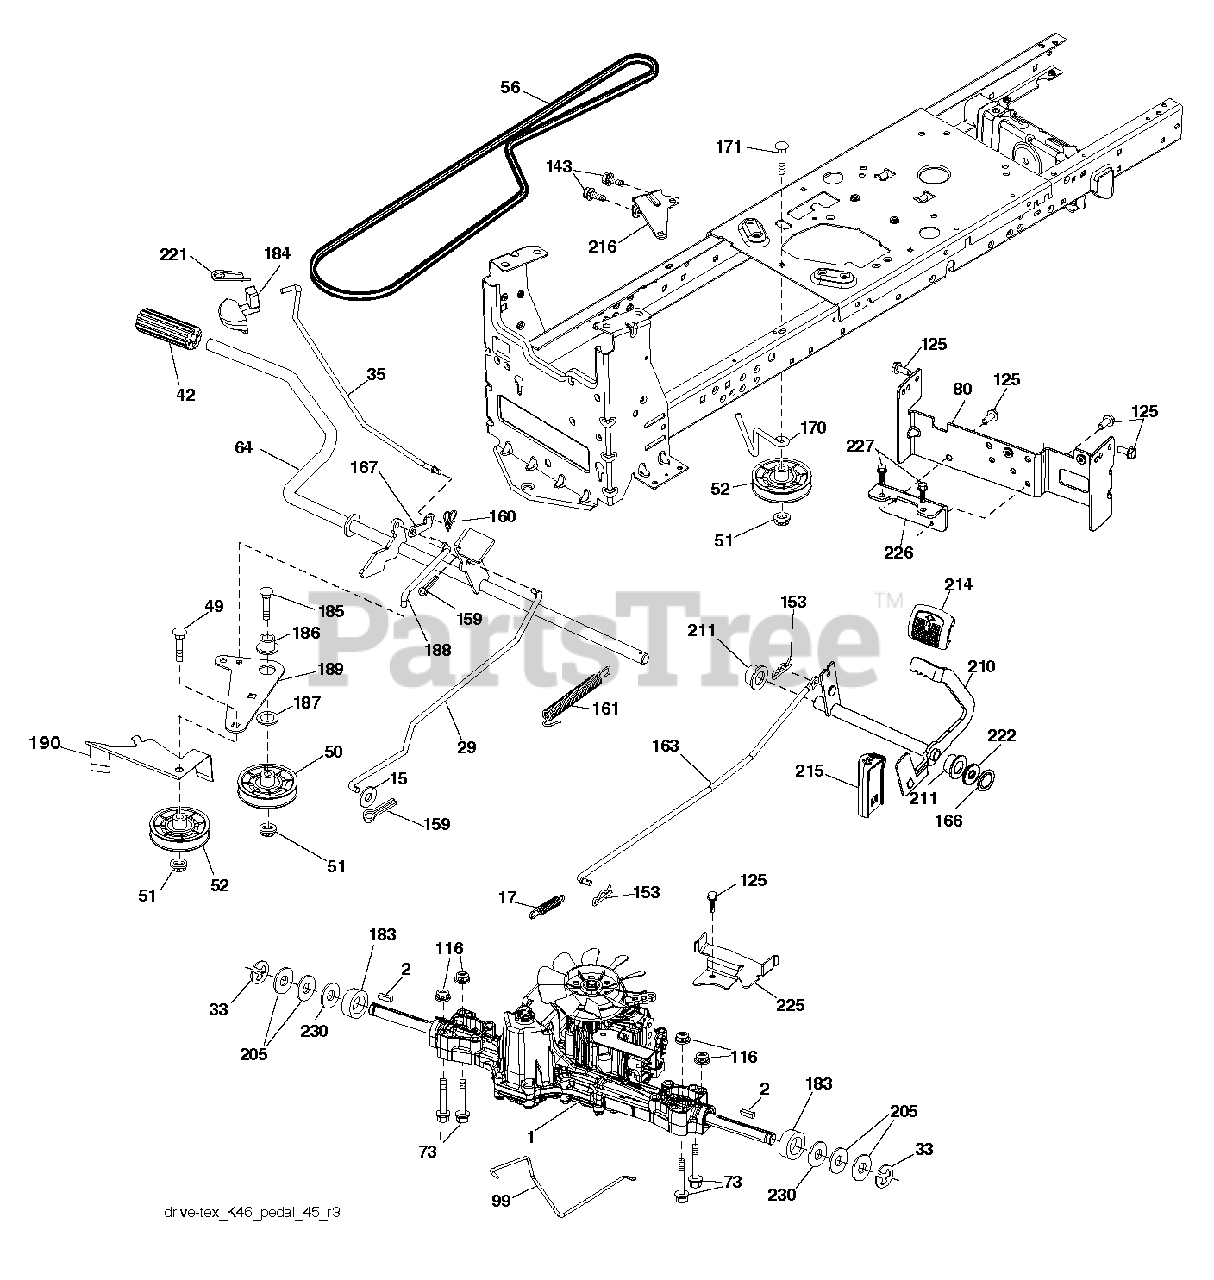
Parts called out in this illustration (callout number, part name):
2	SQUARE KEY
15	WASHER
17	SPRING, BREAK
29	ROD.BRAKE.K46
33	E-RING LT
42	PEDAL COVER T
50	IDLER.FLAT.910.OFFSET
52	IDLER.V-GROOVE.910.OFFSET
64	SHAFT.ASM.PEDAL.BRK.CN
99	ROD.SPRING.BYPASS.K46.LT.Z
116	NUT LOCK HEX FLANGE 5/16-18
125	SCREW
143	SCREW LT
159	COTTER PIN
160	RETAINER CLIP
161	SPRING, RETURN LT
166	NUT.PUSH.625
167	LATCH BRAKE PARKING
170	KEEPER.V-IDLER.CENTER.
183	SPACER AXLE
186	SPACER.RETAINER
188	LINK.CLUTCH.GROUND DRI
189	BELLCRANK.GRDDRIVE.NST
190	KEEPER.BELLCRANK.DRIVE
210	ROCKER.ASM.PEDAL.CONTR
211	BEARING RER
214	PAD PEDAL FORWARD
215	PEDAL.REVERSE.TEX.GT.4
216	BRKT.PULLEY.IDLER.WTEX
221	RETAINER.SPRING.CLIP.H
222	WASHER 21/32 X 1-1/4 X 10 GA.
225	KEEPER.BELT.TRANSAXLE.
226	BRACKET MOUNT TORQUE
